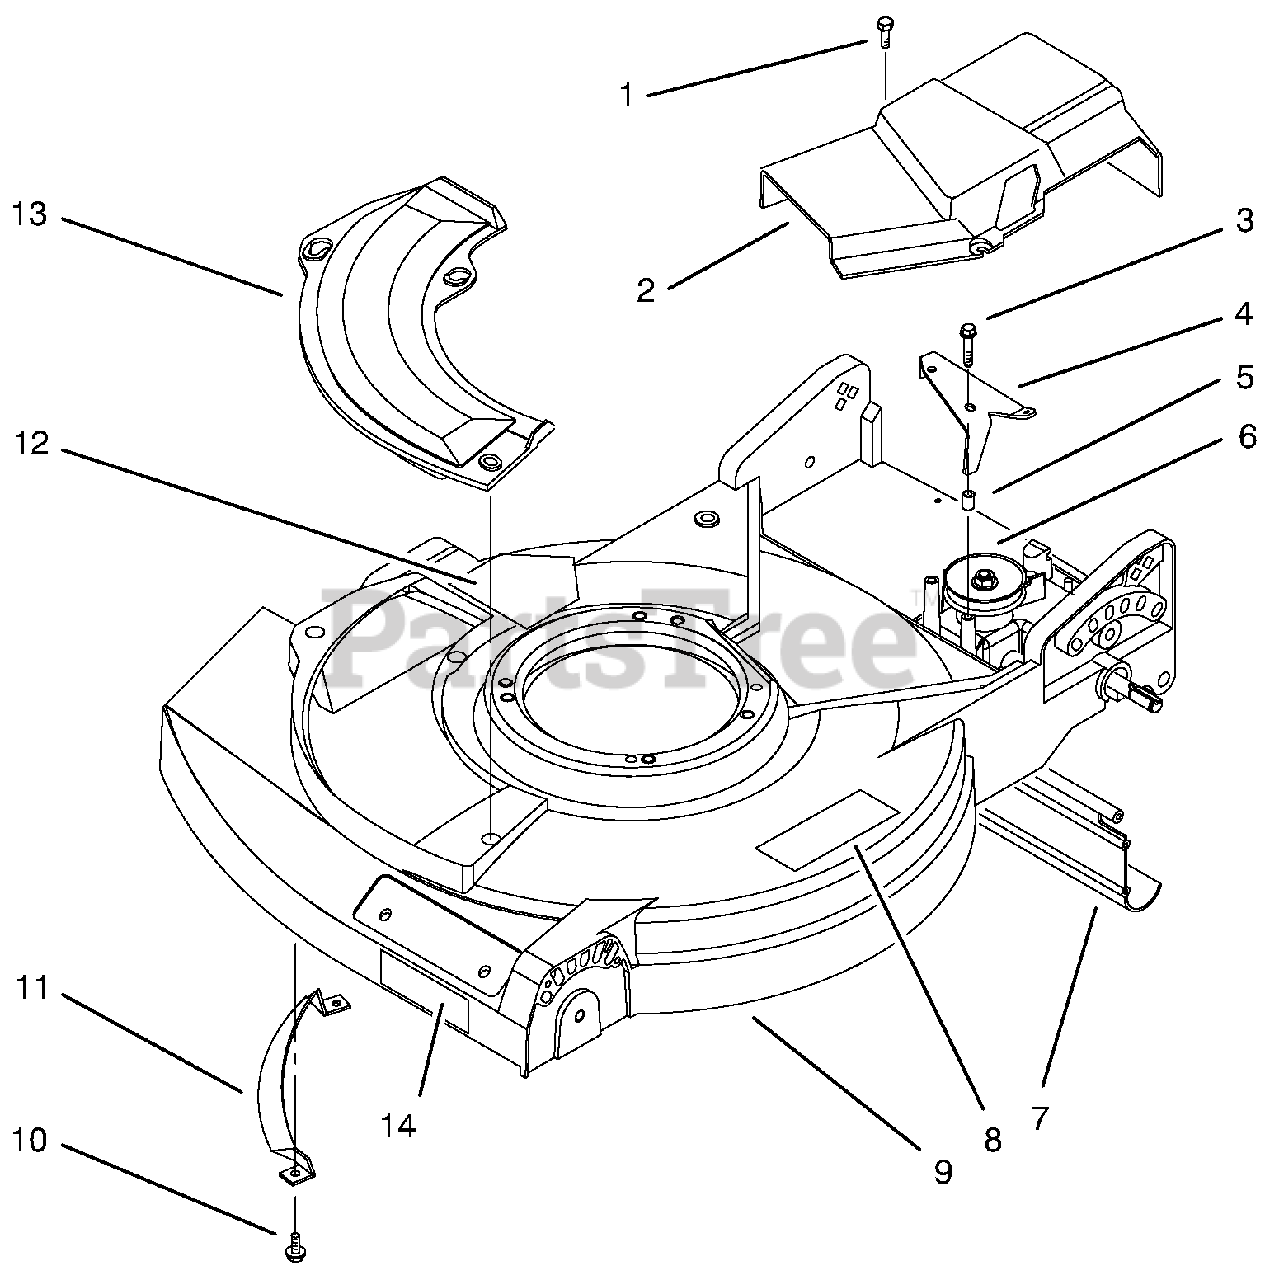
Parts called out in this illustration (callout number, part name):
1	Screw-HexWasher Hd. Thread Forming
2	Cover-Transmission
3	Screw
4	Bracket-Actuator
5	Bushing-Spacer
6	Gear Case Assembly
7	Shield-Trailing
8	Decal-Warning
9	Housing-21" (Incl. Ref. #8, 12, & 14)
10	Screw-Hex Washer Hd.
11	Bar-Toe
12	Decal-Danger
13	Plate-Cover
14	Decal-No Rust
